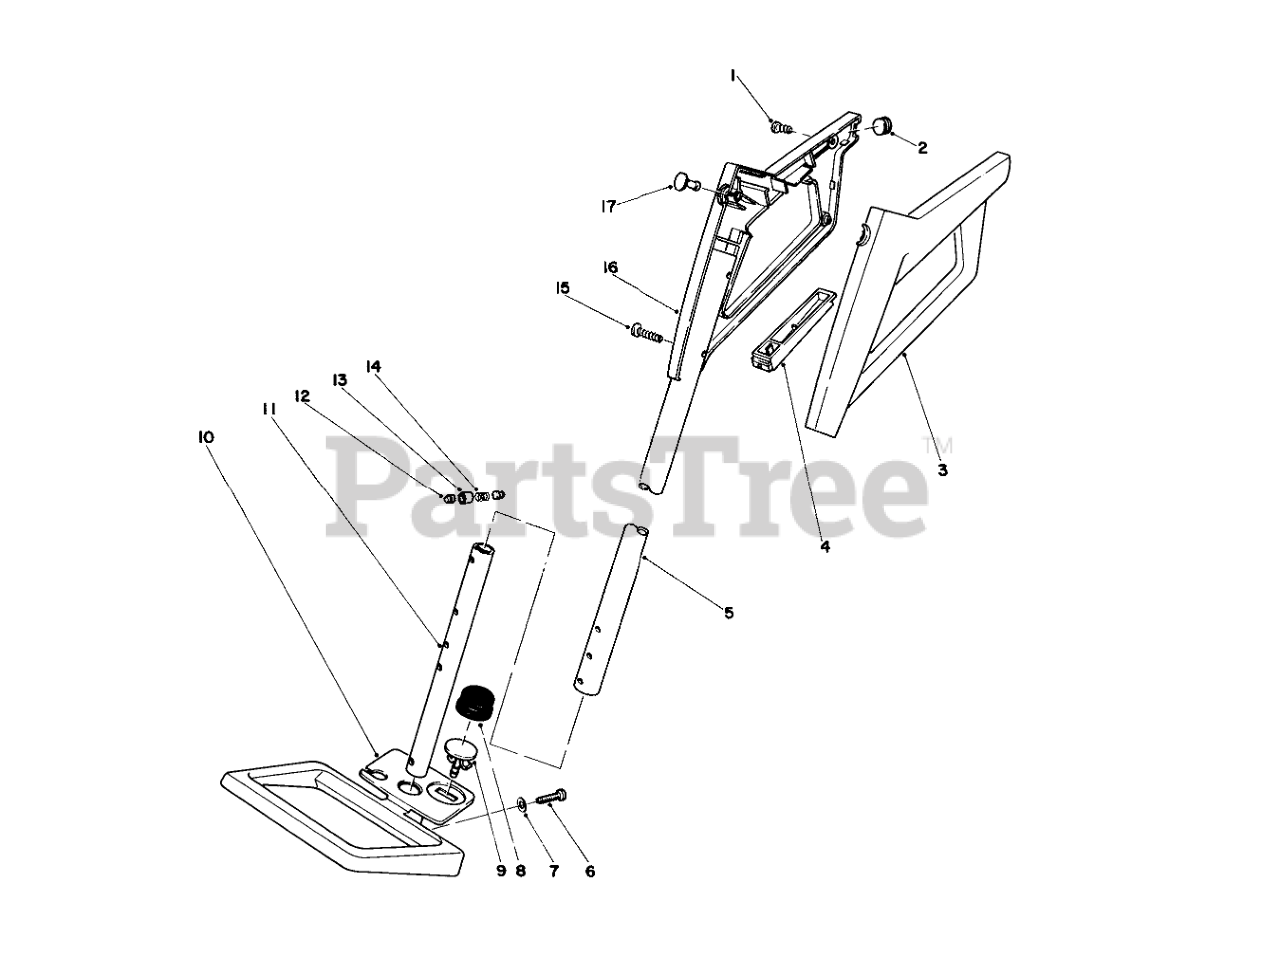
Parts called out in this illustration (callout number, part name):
1	SCREW-PPH
2	Plug-Cord
3	LH CONTROL GRIP
4	COVER HANDLE
5	Tubing-Upper Handle
6	SCREW
7	WASHER-FLAT
8	Bulb Primer
9	BODY-PRIMER
10	HANDLE ASM
11	Tube-Handle, Mounting
12	HANDLE RELEASE
13	Sleeve Release
14	Spring-Compression
15	Screw
16	Grip-Control R.H.
17	PLUG KEY
